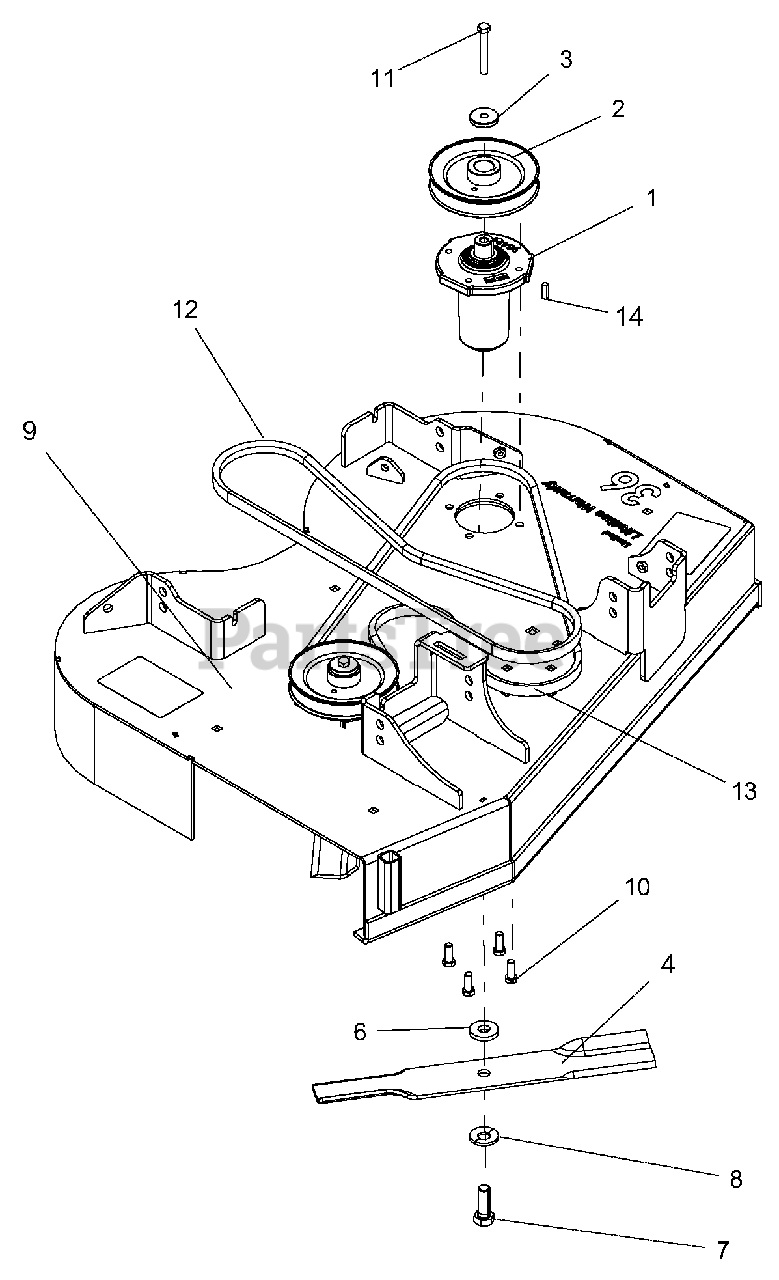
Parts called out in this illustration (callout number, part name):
1	SERVICE, ASM PINDLE- MAINT FREE (SHORT)
2	PULLEY, V-1" ID X 5.75" OD
3	RETAINER, SHEAVE SPINDLE
4	BLADE, 18.000 X .80 LIFT
6	WSHR-FL-STL .630X1.50X.25 YWZC
7	BLT, HEX .62-18X1.75 GR8 YWZC
8	WSHR, BLVL .63X1.625X.14
9	ASM, 36" DECK W/DECALS
10	BLT-HEX .38-16X1.00 GR5 YWZC EP30
11	BLT-HEX .38-16X2.75 GR8 YWZC
12	V-Belt, 5L-RAW EDGE
13	V-BELT, 5L SECTION
14	KEY-SQ .250X.250X.875 RC 40-50
